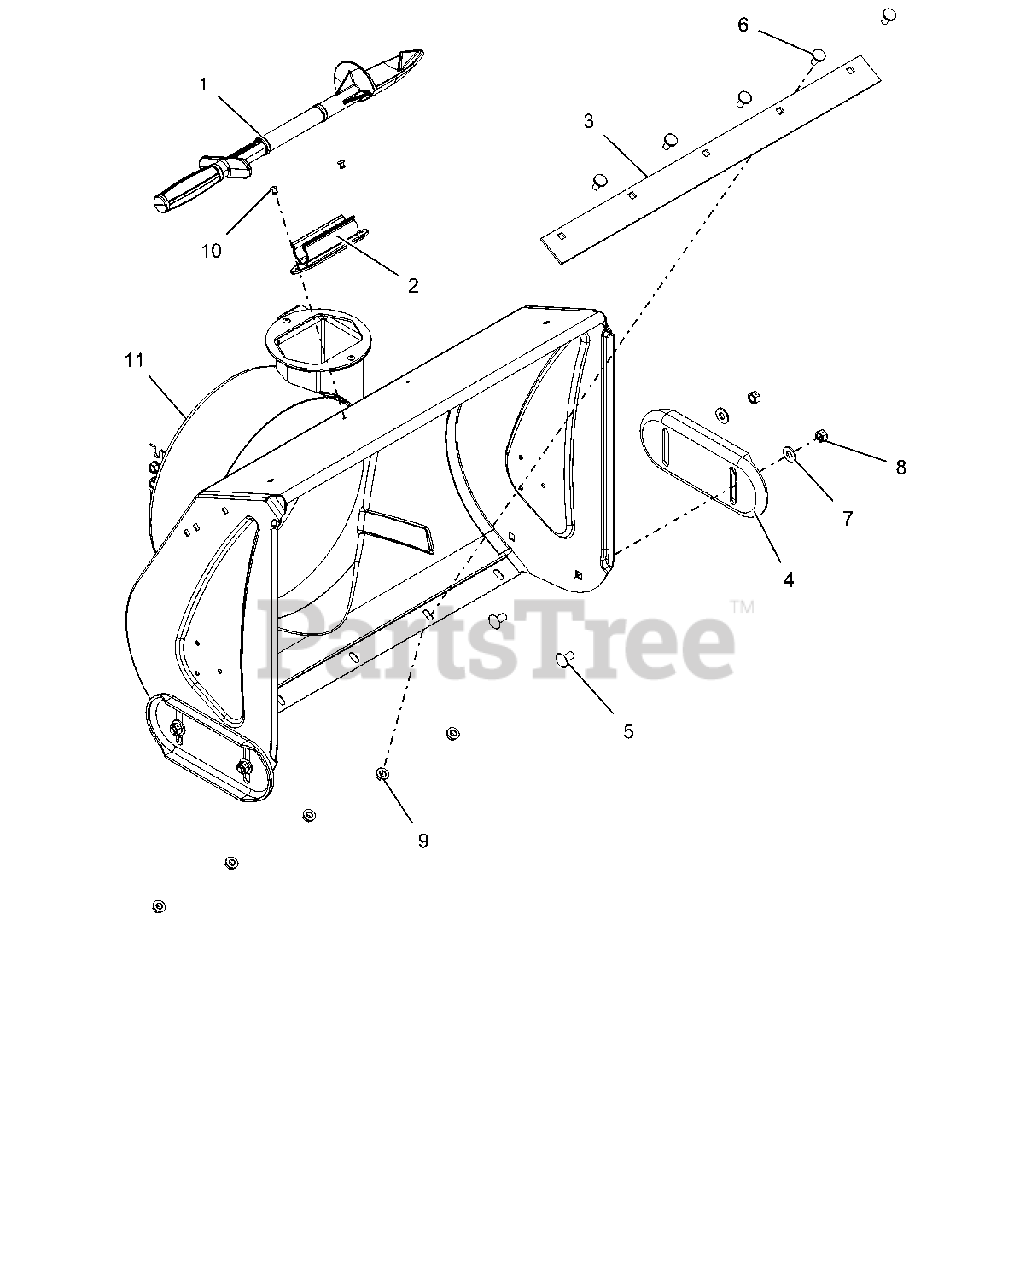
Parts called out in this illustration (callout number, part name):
1	DEVICE, SNOW CLEAN OUT
2	MOUNT, SNOW CLEAN OUT
3	SCRAPER BLADE, 24" COMPACT HI
4	SKID SHOE, REVERSIBLE
5	@BLT-RHDSSQNK .38-16X.75 G5YZ
6	BOLT, MODIFIED HEAD CARRIAGE
7	@WSHR-FL-STL.38X.875X.083 YWZC
8	@NUT-LK-CTR .38-16 YWZC
9	@NUT-LK-TOP-FLG .31-18 YWZC
10	RVT-POP .187 YZ
11	BLOWER HOUSING, 24"
